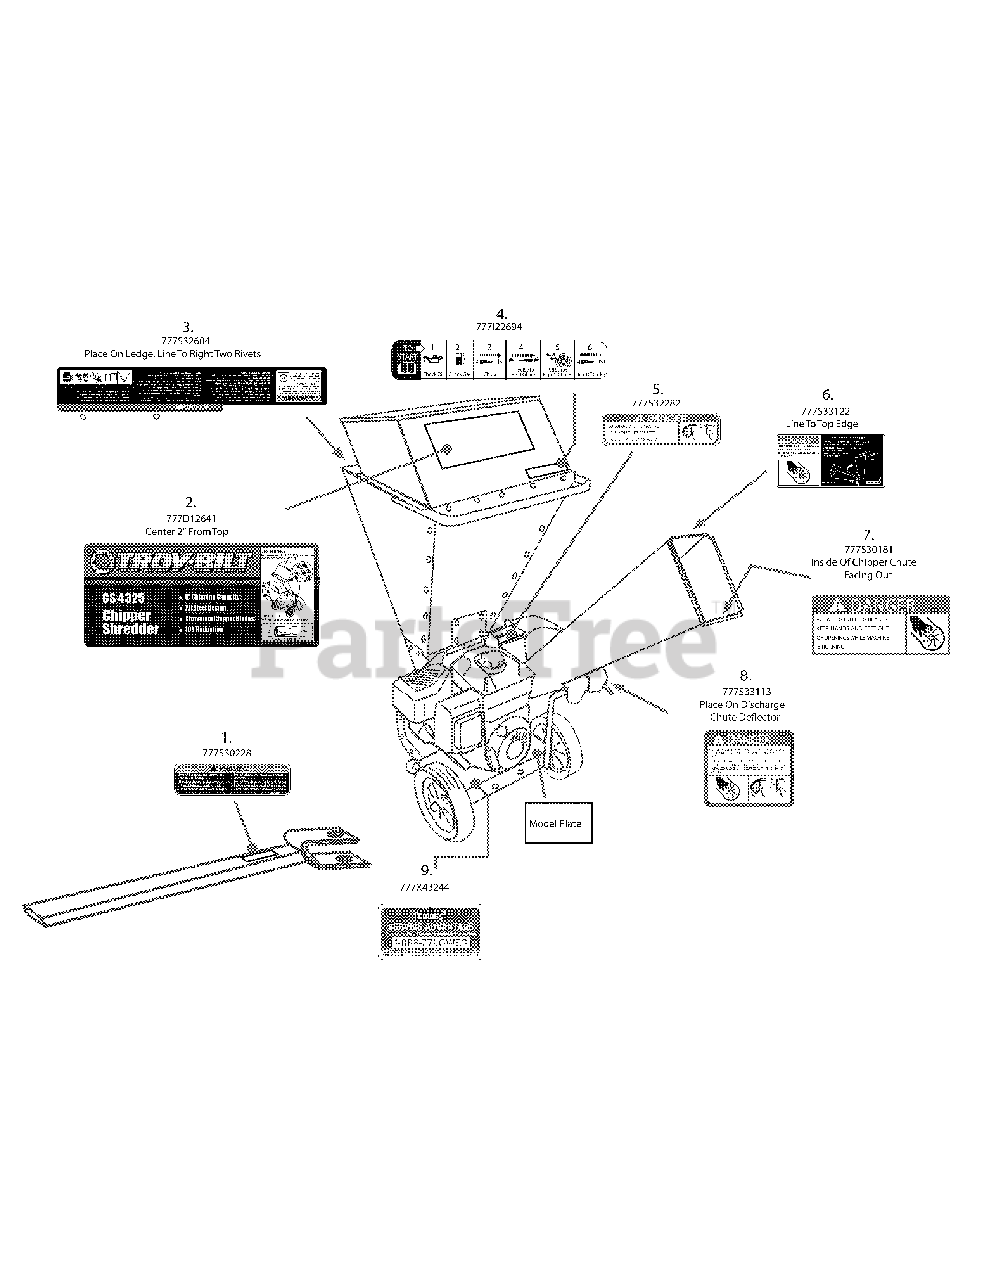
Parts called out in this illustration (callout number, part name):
1	LABEL-TOW BAR
2	LABEL-FRONT CS 4325/TROY
3	LABEL-VERT/CS:HOPPER
4	LABEL-START INSTRUCT
5	LABEL-CHUTE
6	LABEL-CHIPPER/SHREDDER DANGER
7	LABEL-TOP CHUTE DANGER
8	LABEL-CHIPPER SHREDDER CHUTE
9	LABEL-LOWES:SERVICELBL
